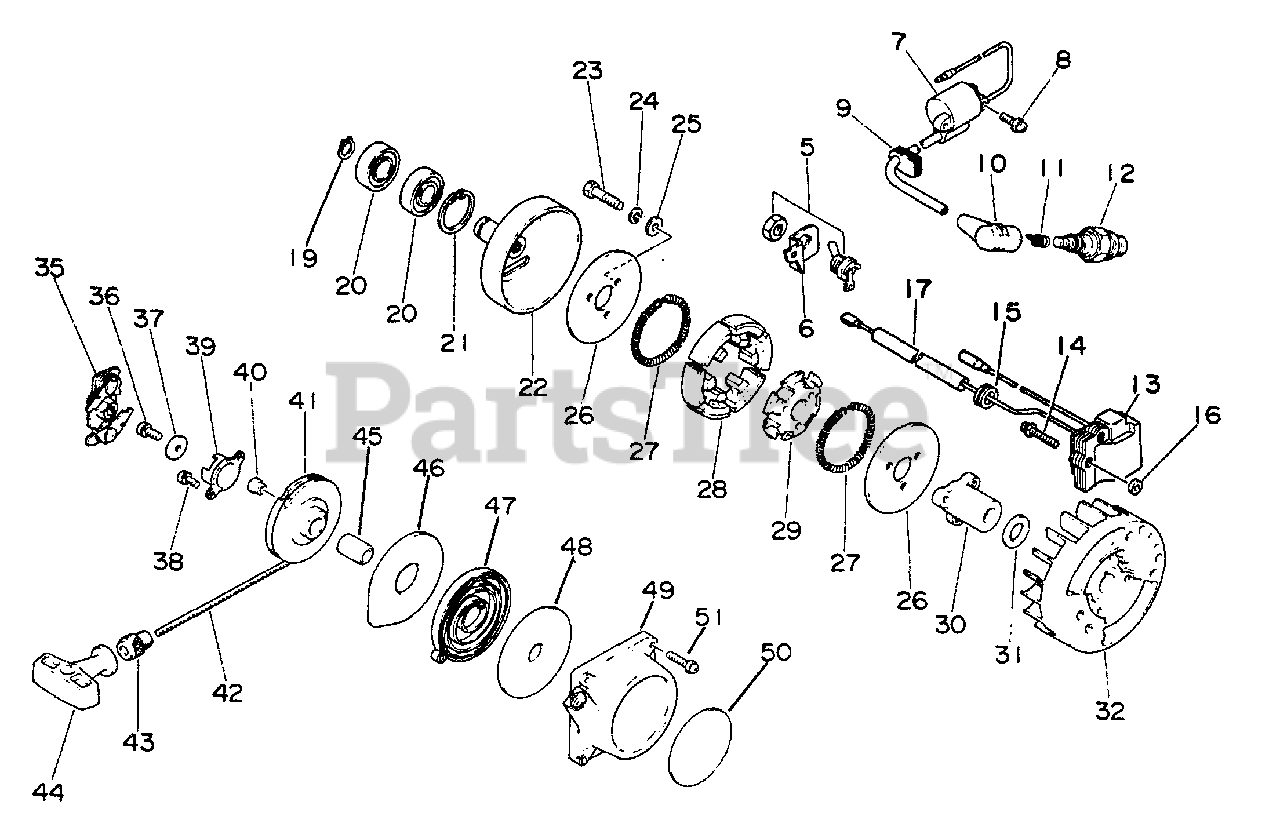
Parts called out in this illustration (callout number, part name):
5	SWITCH, IGNITION
6	BRACKET, SWITCH
7	COIL, IGNITION
8	SCREW 4×14
10	CAP, SPARK PLUG
11	TERMINAL, SPARK PLUG
12	SPARK PLUG - BPM7A
13	COIL, IGNITION
14	SCREW 4×22
17	TUBE
19	RING, RETAINING 15
20	BEARING, BALL 6203
21	RING, SNAP 35
22	DRUM, CLUTCH
23	BOLT - 5×25
24	WASHER, SPRING 5
25	WASHER, FLAT 5.5×10×0.8
26	PLATE, SIDE
27	SPRING, CLUTCH
28	SHOE, CLUTCH
29	BOSS, CLUTCH
30	ADAPTER
31	WASHER
32	FLYWHEEL
35	STARTER PAWL ASSY
36	SCREW 5×10
37	WASHER 5.2×16×1.0
38	SCREW 4×8
39	PAWL CATCHER
40	CLIP, STARTER ROPE
41	REEL, ROPE
42	ROPE, STARTER 3.5×850
43	GUIDE, ROPE
46	PLATE, SIDE
47	SPRING, RECOIL
48	PLATE, SIDE
49	CASE, STARTER
50	LABEL - ECHO
51	SCREW 4×20
